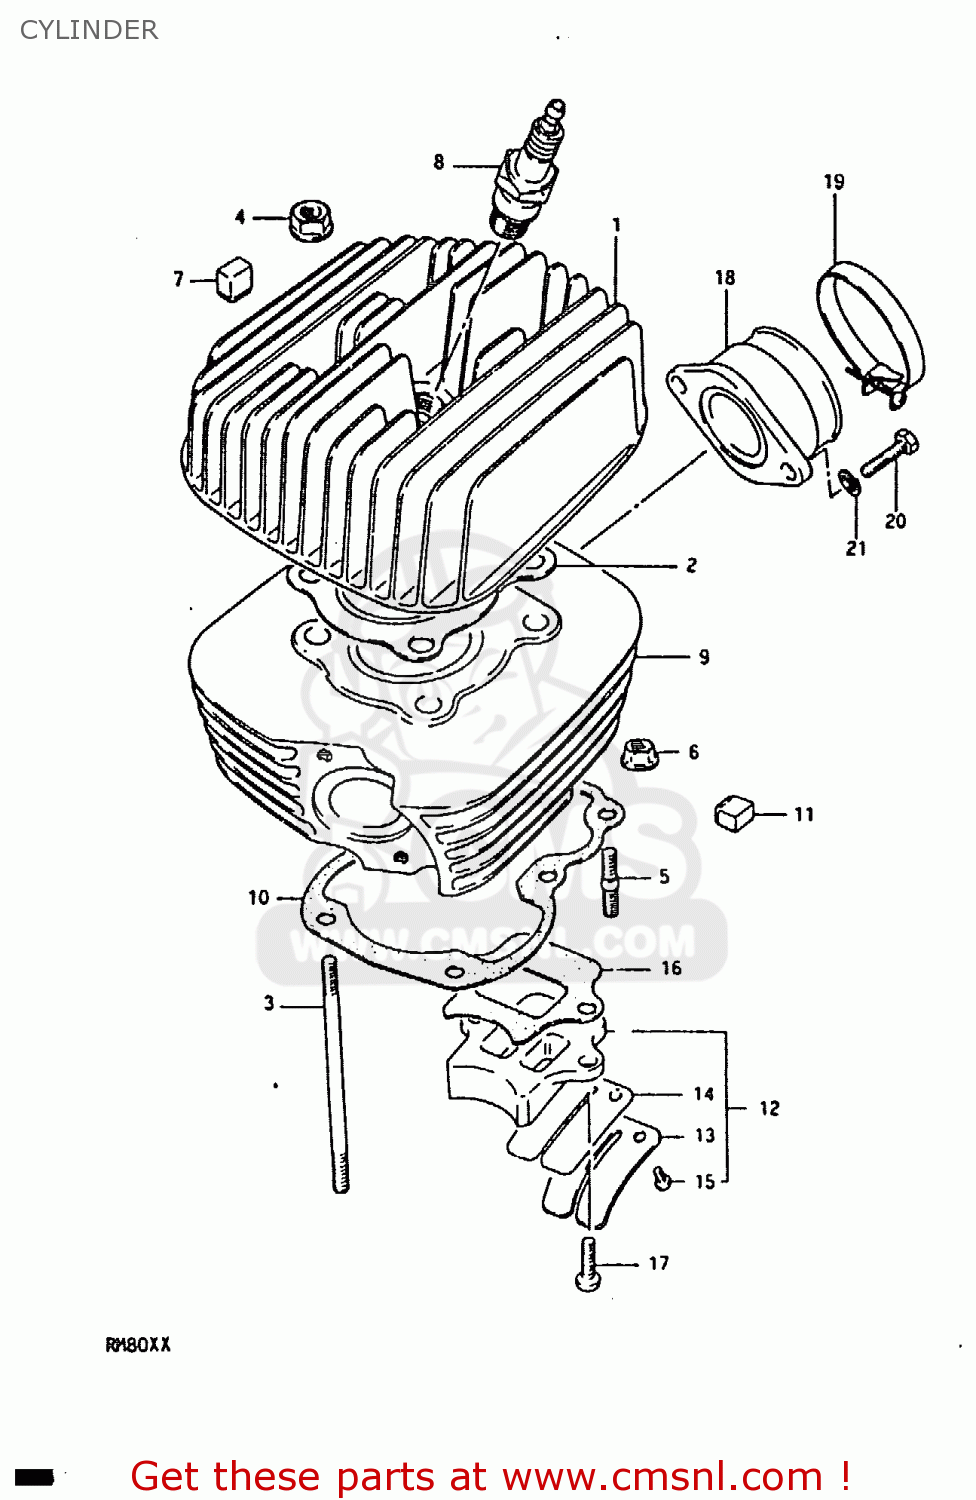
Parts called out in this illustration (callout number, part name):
1	HEAD,CYLINDER
2	GASKET,CYLINDER HEAD (NAS)
3	BOLT,STUD
4	NUT
5	STUD 6X20
6	NUT
7	PAD,CYLINDER
8	PLUG,SPARK
9	CYLINDER (@F49)
10	GASKET,CYLINDER (MCA)
11	PAD,CYLINDER
12	VALVE ASSY,REED
13	STOPPER,REED VALVE
14	VALVE,REED
15	SCREW,REED VALVE
16	GASKET,REED VALVE (MCA)
17	SCREW
18	PIPE,INTAKE
19	CLAMP
20	BOLT
21	LOCK WASHER
